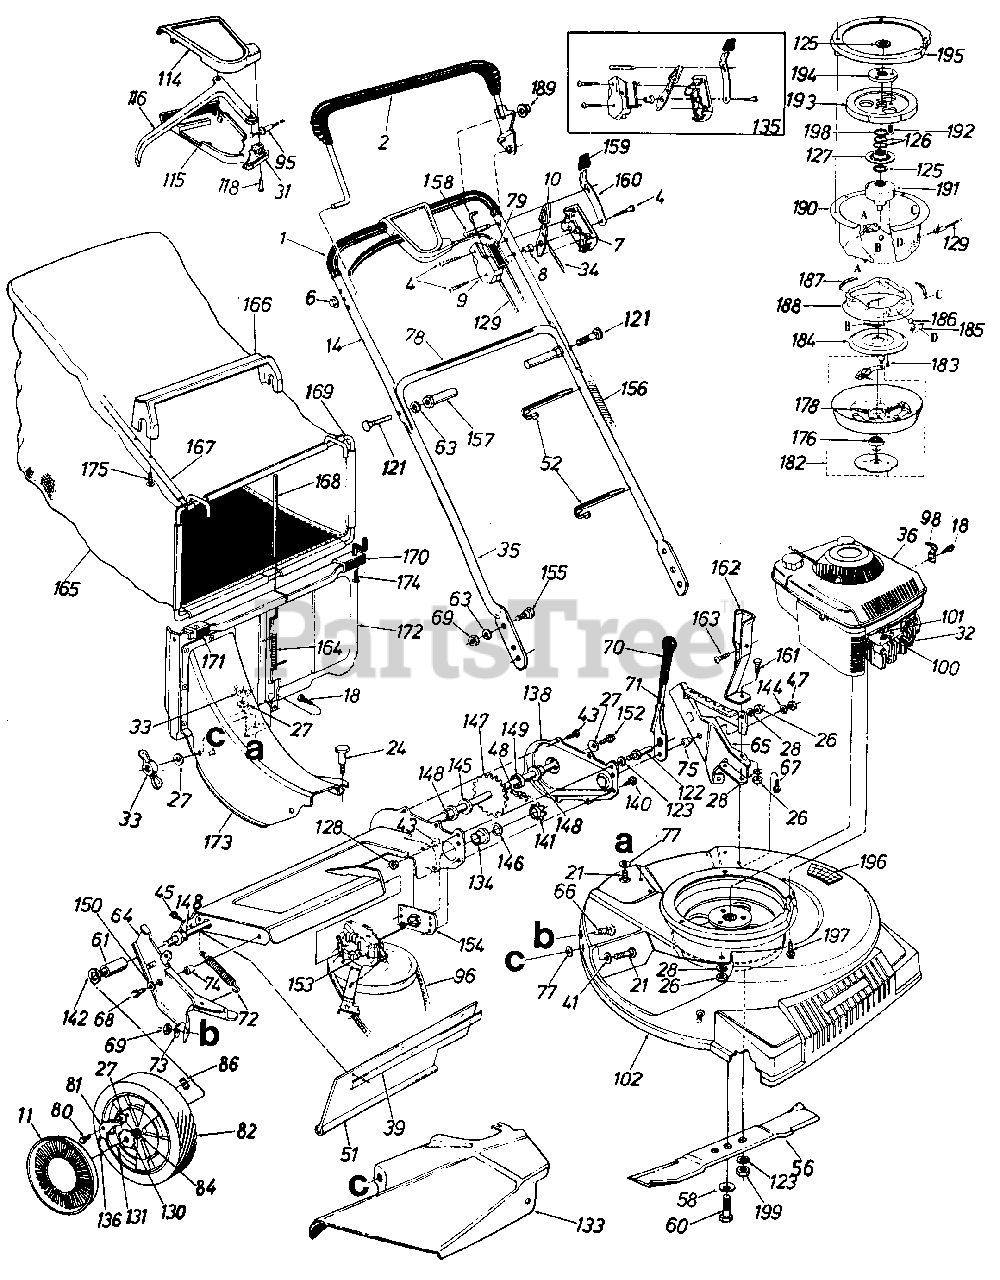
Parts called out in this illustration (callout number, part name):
2	Control Handle Ass'y. L.H.
4	Truss Mach. Scr. #12 x 1.50" Lg.
6	Push Cap
7	Control Panel Half
8	Control Disc Pin
9	Clutch Panel Half
10	Throttle Control Lever
11	Hub Cap
14	Upper Handle Chrome
18	Hex B-Tap Scr. #10 x .38"
21	Carriage Bolt 1/4-20 x .62"
24	Shoulder Bolt .312 Dia. x .18 Lg. Special
26	Hex Nut 1/4-20 Thd.
27	Bell-Wash. 1/4" I.D.
28	L-Wash. 1/4" I.D.
31	S.P. Control Cover
32	Spark Plug Insulator
33	Wing Nut
34	Throttle Control Wire 58"
35	Lower Handle Chrome
36	Engine
39	Retaining Strip
41	Fl-Wash. .344" I.D. x .62"
43	Hex B-Tap Scr. 1/4" x .38"
45	Hex AB-Tap Scr. 1/4 x .62"
47	Hex Patch L-Nut 3/8-24 Thd.
48	#48 Chain .500" Pitch x .30 Links
51	Rear Flap 3.75" x 17.30" Lg.
52	Cable Tie
56	21" Blade
58	Bell-Wash. .460" I.D. x .880"
60	Hex Bolt 7/16-20 x 2.0"
61	Spacer.513" I.D.
63	L-Wash. 5/16" I.D.
64	R.H. Handle Wheel Brkt. Ass'y.
65	L.H. Handle Wheel Brkt. Ass'y.
66	Carriage Bolt 5/16-18 x .62"
67	Hex Wash. Hd. B-Tap Scr. 5/1 6-1 8
68	Hex Wash. Hd. TT-Tap Scr. 3/8-1 6
69	Hex Nut 5/16-18 Thd.
71	Height Adj. Lever
72	Extension Spring 3.80" Lg.
73	Bell-Wash. 5/16" I.D.
74	Spacer.385" I.D.
75	Shld. Spacer.5" Dia.
77	Bolt Retainer 1/4 x .50" O.D.
78	Instruction Label
79	Control Label
80	Shld. Scr. .342" Dia. x .268
81	Pawl
82	Wheel Ass'y. Comp. Rear
84	Sleeve Bearing .503" I.D.
86	Flat Nut 1/4-20 Thd.
95	S.P. Cable 50" Lg.
96	"V"-Belt
98	Casing Clamp
100	Hex B-Tap Scr. #10 x .62"
101	Casing Clamp
115	Self-Propelled Control Cover
116	Control Lever
118	Fl-"C"-Sunk Hd.-Tap Scr. #10 x .75" Lg.
121	Curved Carr. Bolt 5/16-18 x 1.75" Lg.
122	Shld. Pin 1.43" Lg.
123	L-Wash. 3/8" I.D.
125	Serrated Wash. 1.0" I.D.
126	Wave Wash. 1.005" I.D.
127	Serrated Pulley Half
128	Hex Nut 3/8-24 Thd.
129	Clutch Cable 49"
130	Ratchet Wheel 1.62" O.D.
131	Cotter Pin 1/8" Dia. x 1"
133	Side Chute Deflector Ass'y.
134	Flange Bearing
135	Kit Control Housing Comp.
136	Spring Nylon
138	Chain Cover
140	Hex Wash. S-Tap Scr. 1/4-20 x.50" Lg.
141	Sprocket Shaft Ass'y.
142	Fl-Wash. .510" I.D. x 1.0"
144	Fl-Wash. .385" I.D. x .87"
145	Fl-Wash. .51 " I.D. x 1.0"
146	Fl-Wash. 3/8" I.D.
147	Rear Shaft Ass'y. 21.94" Lg.
148	Hex Flange Brg. .506" I.D.
149	Fl-Wash. .531" I.D. x .9301'
150	Fl-Wash. .531" I.D.
152	Hex Bolt 1/4-20 x .62" Lg. (Grade 5)
153	Transmission Comp.
154	Hex Bearing Cup
155	Truss Mach. Scr. 5/16-18 x .75" Lg.
156	Plastic Tubing
157	Catcher Support Pin
158	Lock Pin .314" Dia. x 1.75"
159	Spring Lever Knob
160	Lockout Spring
161	Hex Bolt 1/4-20 x .50" Lg.
162	Grass Catcher Bracket
163	Truss Mach. Scr. 1/4-20 x .50" Lg.
164	Torsion Spring
165	Grass Bag
166	Bag Handle
169	Front Catcher Frame
170	Door Clip
171	Panel Bag Clip
172	Chute Door
173	Top Discharge Chute Ass'y.
174	Hex AB-Tap Scr. 1/4 X .75"
175	Hex AB-Tap Scr. #12 x 1.25" Lg.
176	Ball Bearing
178	Compression Spring
182	Clutch Blade Housing Ass'y.
183	Hex Wash. TT-Tap Scr 1/4-20 x .75" Lg.
184	Brake Cup Cone
185	Ball Block
186	Steel Ball
187	Ext. Spring 1.75" Lg.
188	Clutching Cone
189	Push Cap
190	Clutch Housing
191	Fixed Pulley Adapter
192	Flat Hd. B-Scr. 1/4-20 x .62"
193	Flywheel
194	Flywheel Adapter
195	Engine Mtg. Cover Plate Ass'y.
196	Rubber Foot Pad
197	Hex Wash. Hd. Tap Scr. 3/8-16 x 1.50" Lg.
198	Serrated Wash. 1.0" I.D.
199	Hex Nut 3/8-24 Thd. (Grade 8)
